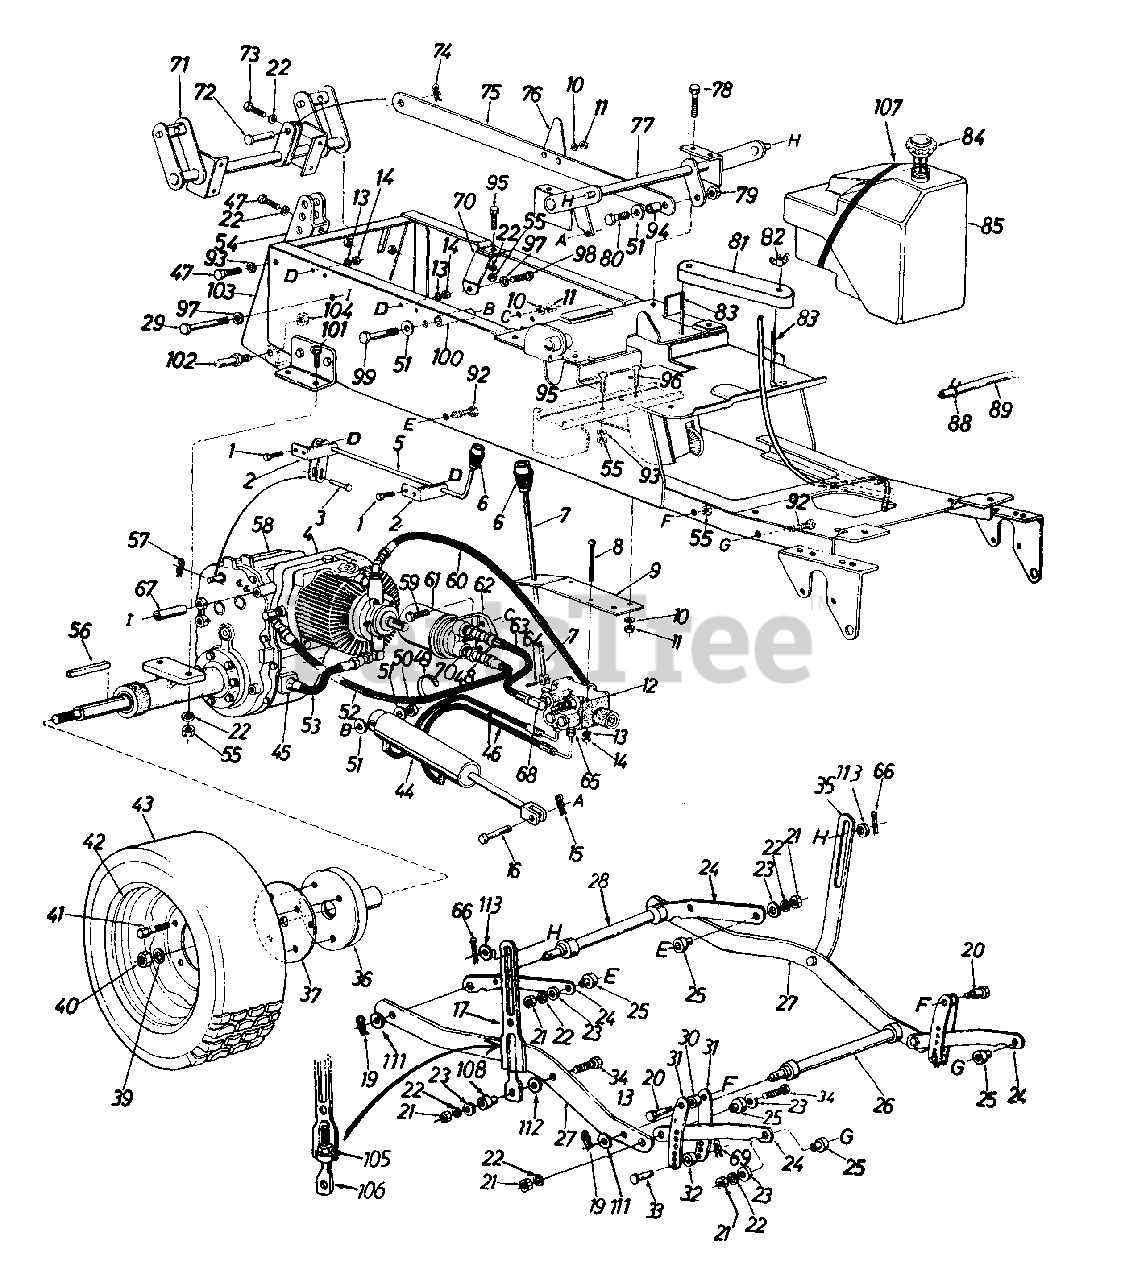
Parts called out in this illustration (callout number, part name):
1	Hex Bolt 1/4-20 x .75" Lg.
2	Hi-Lo Speed Control Brkt.
3	Clevis Pin 1/4" Dia.
4	Hydrostatic Pump Comp.
5	Hi-Lo Control Handle Ass'y.
6	Shift Knob
7	Cylinder Control Handle Ass'y.
8	Truss Mach. Scr. 1/4-20 x 3.00" Lg.
11	Hex Nut 5/16-18 Thd.
12	Valve Ass'y. Comp.
13	L-Wash. 1/4" I.D.
14	Hex Nut 1/4-20 Thd.
15	Hairpin Cotter 1/2" Dia.
16	Clevis Pin 1/2" Dia.
17	Adj. Deck Link
18	Fl-Wash. .62" I.D. x 1.12"
19	Hairpin Cotter
20	Shld. Bolt .498" Dia. x .66"
21	Hex Nut 3/8-24 Thd.
22	L-Wash. 3/8" I.D. - H.D.
23	Fl-Wash. .38" I.D. x 1.00"
24	Lift Arm
25	Shld. Spacer .385" I.D.
26	Cross Shaft Ass'y. - Front
29	Hex Bolt 1/2-13 x 2.75"
30	Collar .50" I.D. x 1.0"
31	Index Brkt.
32	Spacer .38" I.D. x 1.0" O.D.
33	Clevis Pin 3/8" Dia.
34	Hex Bolt 3/8-24 x 1.50" Lg. - Grade 5
39	L-Wash. 3/4" I.D.
40	Hex Ins. L-Nut 3/4-16 Thd.
41	Wheel Lug Bolt
44	Hydraulic Cylinder
45	7/8-14 UNF-2A Thd. 5/8 Tube Fitting
46	Valve to Cylinder Hose - 20"
47	Hex Bolt 3/8-16 x .75" Lg. - Grade 5
48	Bushing Reducer 1/2-14 NPTF to 3/8-18 NPTF
49	Cable Tie
50	Hex Jam Nut 1/2-20 Thd.
51	Fl-Wash. .50" I.D. x 1.25
52	Filter Return Hose 24" Lg.
53	Pump Tube Ass'y.
54	Hitch Brkt.
55	Hex Nut 3/8-16 Thd.
56	Sq. Key 1/4" x 1/4" x 2"
57	Hairpin Cotter 1/4" Dia.
58	Peerless Transaxle
59	Hex Bolt 5/16-18 x 1.25"
60	Pump to Valve Hose
61	Fram Filter Ass'y. PH-16
62	Filter Base
63	Valve to Filter Hose - 8.38"
64	Spring Pin Spiral 1/8" Dia.
65	Flare Adapter
66	Cotter Pin 1/8" Dia. x 1.0"
67	Spacer
68	Adapter 9/16-18 to 9/16-18
69	Hairpin Cotter
70	Transmission Brace
71	Rear Lift Shaft Ass'y.
72	Clevis Pin
73	Hex Scr. 3/8-16 x 1.00" Lg. Grade 5
74	Cotter Pin 1/8" Dia. x 1.25"
75	Push Bar Ass'y.
76	Position Indicator
79	Hex Cent. L-Nut 1/2-20 Thd.
80	Hex Scr. 1/2-20 x 1.25" Lg.
81	Battery Cover
82	Wing Nut 1/4-20 Thd.
83	Battery Hold Down Rods
84	Gas Tank Cap
85	Gas Tank Ass'y.
88	Gas Line Clamp 1/2"
89	Gas Line 46" Lg.
92	Hex Scr. 3/8-24 x 1.50" Lg.
93	L-Wash. 3/8" Scr.
94	Push Bar Sleeve
95	Hex Scr. 3/8-16 x 1.00" Lg. - Grade 5
96	Hex Scr. 5/16-18 x .75" Lg.
97	L-Wash. 1/2" Scr.
98	Hex Scr. 1/2-13 x 1.25" Lg.
99	Hex Scr. 1/2-20 x 3 1/2" Lg. - Grade 5
100	Spacer for Cylinder
101	Hex Scr. 3/8-16 x 1.75" Lg.
102	Link Clevis Pin
103	Hitch Plate Ass'y.
104	Hex Cent. L-Nut 5/8-18 Thd.
105	Hex Nut 1/2-13 Thd.
106	Eye Bolt
107	Tie Strap
108	Spacer .385" I.D.
111	Fl-Wash. .63" I.D. x .93" O.D.
112	Fl-Wash. .381" I.D. x .87" O.D.
113	Fl-Wash. .5" I.D. x 1" O.D.
